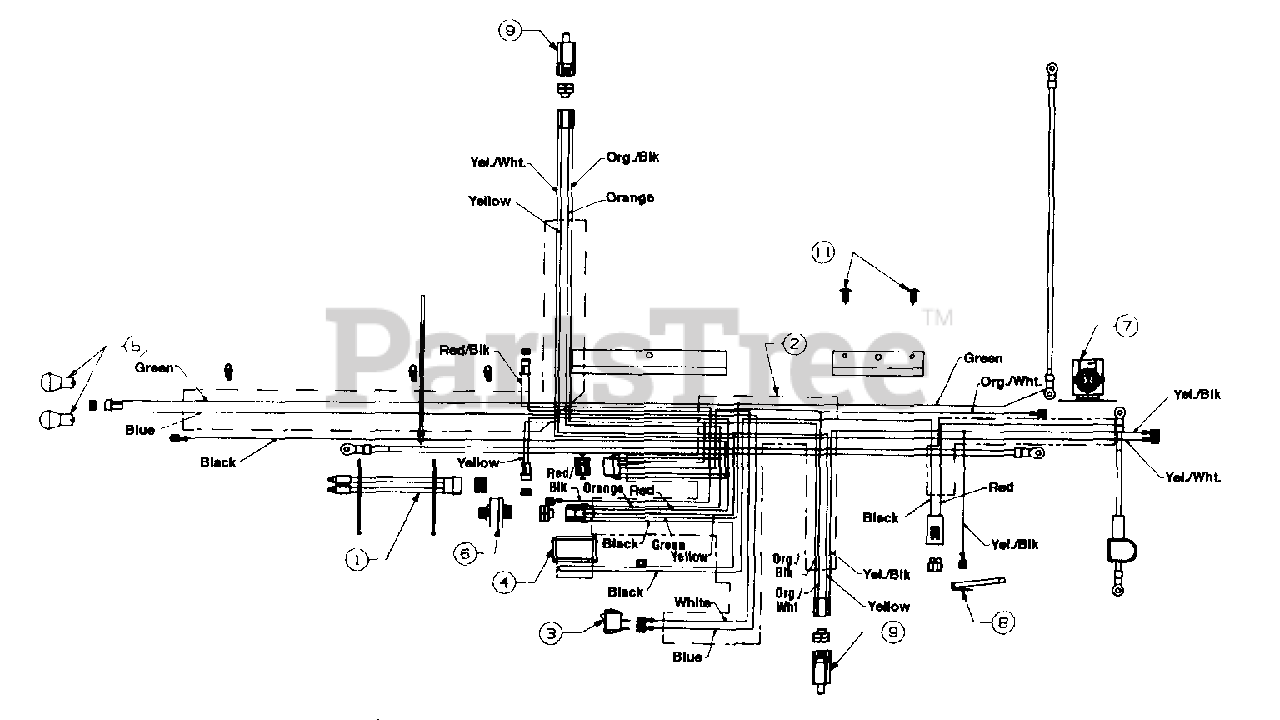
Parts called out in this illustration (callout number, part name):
1	Wire Harness (Monitor)
2	Wire Harness w/Light Switch, Amp and Monitor
3	Light Switch
4	Ammeter
5	Bulb (Headlight)
6	Ignition Switch
7	Solenoid
8	Safety Switch (Reverse)
9	Safety Switch
11	Ratchet
